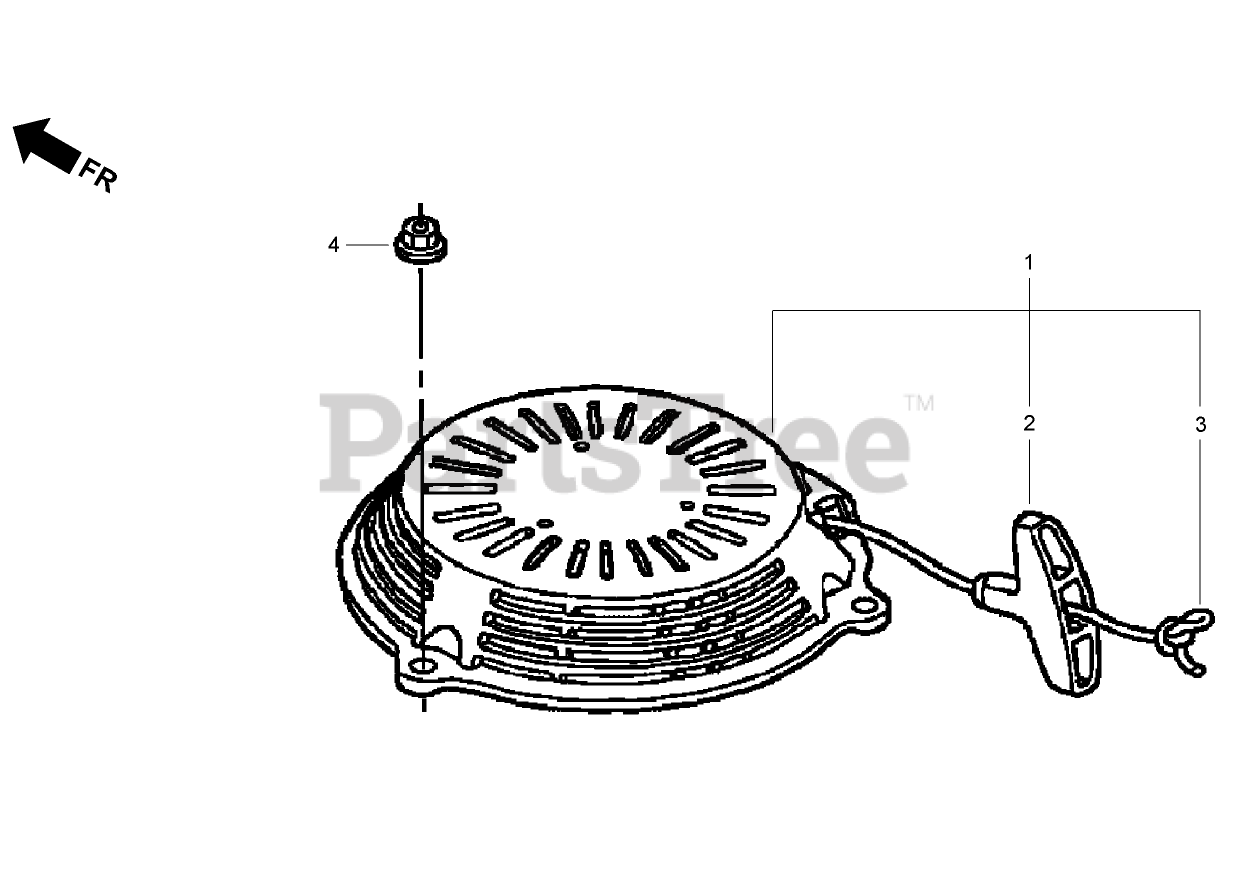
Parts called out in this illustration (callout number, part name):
1	RECOIL STARTER ASM (N H1) (BLACK)
2	GRIP-STARTER
3	ROPE-STARTER, RECOIL (LONG TYPE)
4	NUT-FLANGE (6MM)
